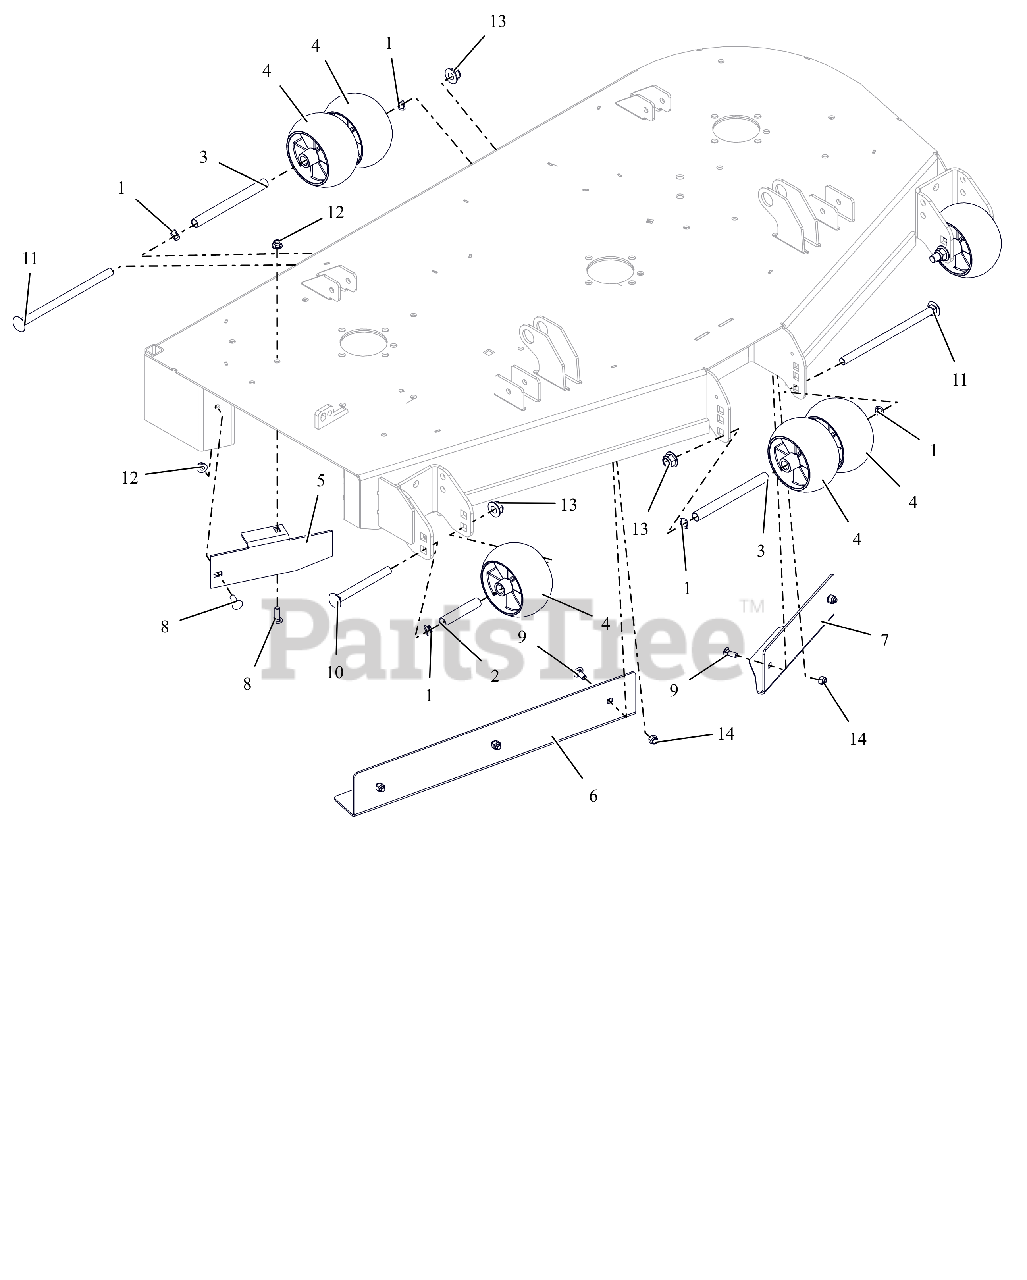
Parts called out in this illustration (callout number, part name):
1	WAVE WASHER .531X.781X.125FH
2	SPACER, .510X.625X3.35
3	SPACER, .510X.625X6.50
4	ANTI-SCALP WHEEL - 5X3 CTR
5	BAFFLE, DISCHARGE, 52"
6	BAFFLE, 52" RH VACUUM (RED)
7	BAFFLE, 52" LH VACUUM (RED)
8	BLT,RHSN .31-18X1.00 G5 ZCC
9	BLT,RHSN .31-18X.75 G5 ZCC
10	BLT, RHSN .50-13X5.00 G5 ZCC
11	BLT, RHSN .50-13X8.50 G5 ZCC
12	NUT,NYL-FLG .31-18 GF ZCC
13	NUT,NYL-FLG .50-13 GF ZCC
14	NUT,NYL .31-18 G5 ZCC
